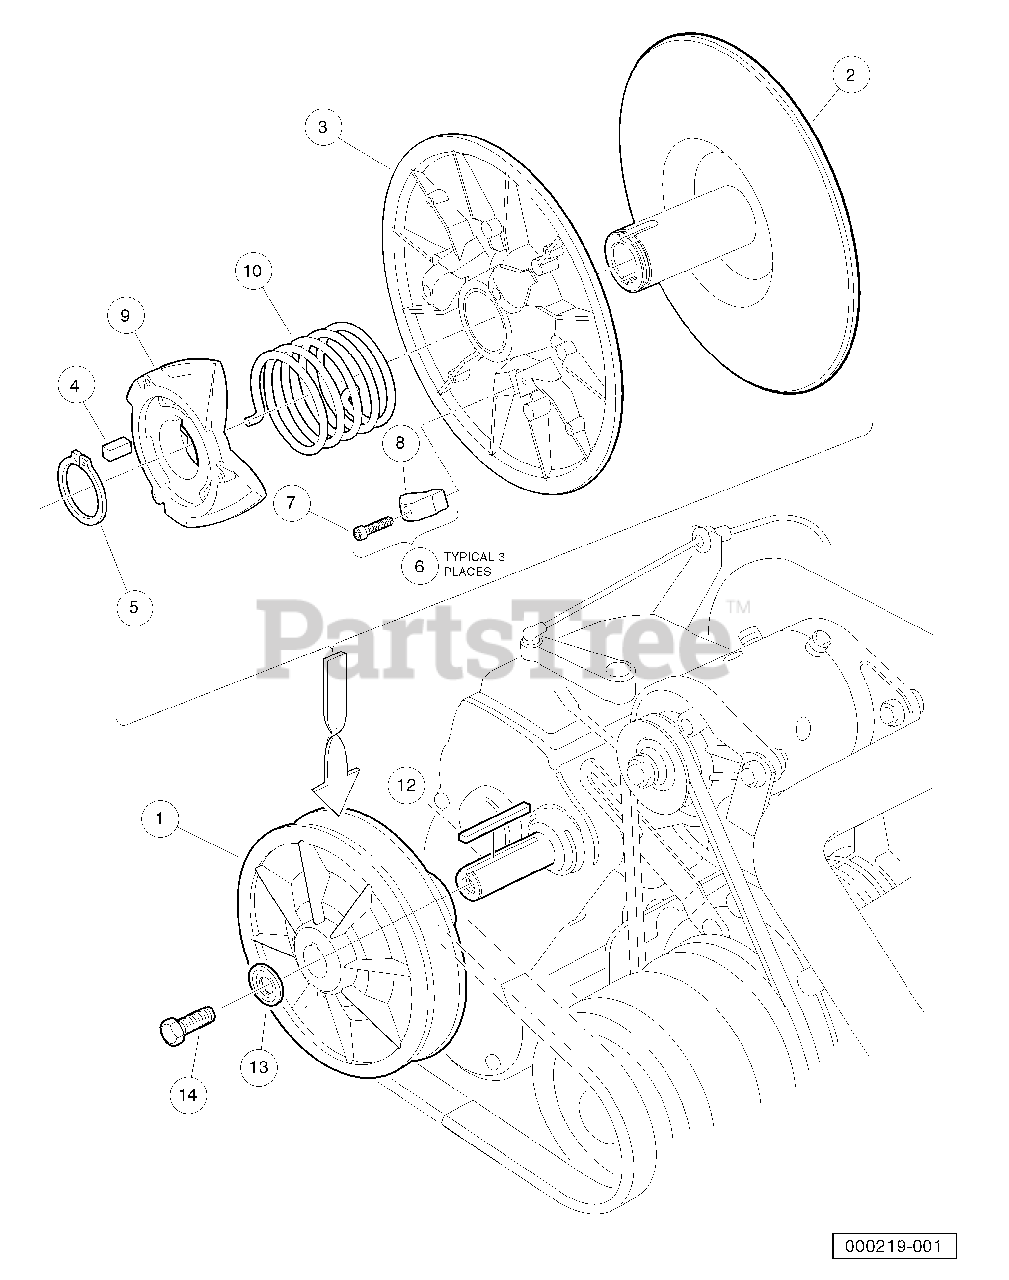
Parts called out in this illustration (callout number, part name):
1	Assembly, Driven Clutch
2	Fixed Face Assy, Driven Clutch
3	Movable-Face Assembly with Bushing
4	Key, Driven Clutch
5	Ring, Retaining
6	Kit, Driven Clutch Button
7	Screw, #8-32 X 3/4 Socket-Head Cap
8	Button, Drive
9	Cam, Driven Clutch
10	Spring, Driven Clutch, Reversed
11	Kit, Clutch Repair
12	Key, 3/16 Sq X 1.50"
13	Washer, Driven Clutch
14	Screw, 5/16-18 X 3/4 Hex-Head with Patch
